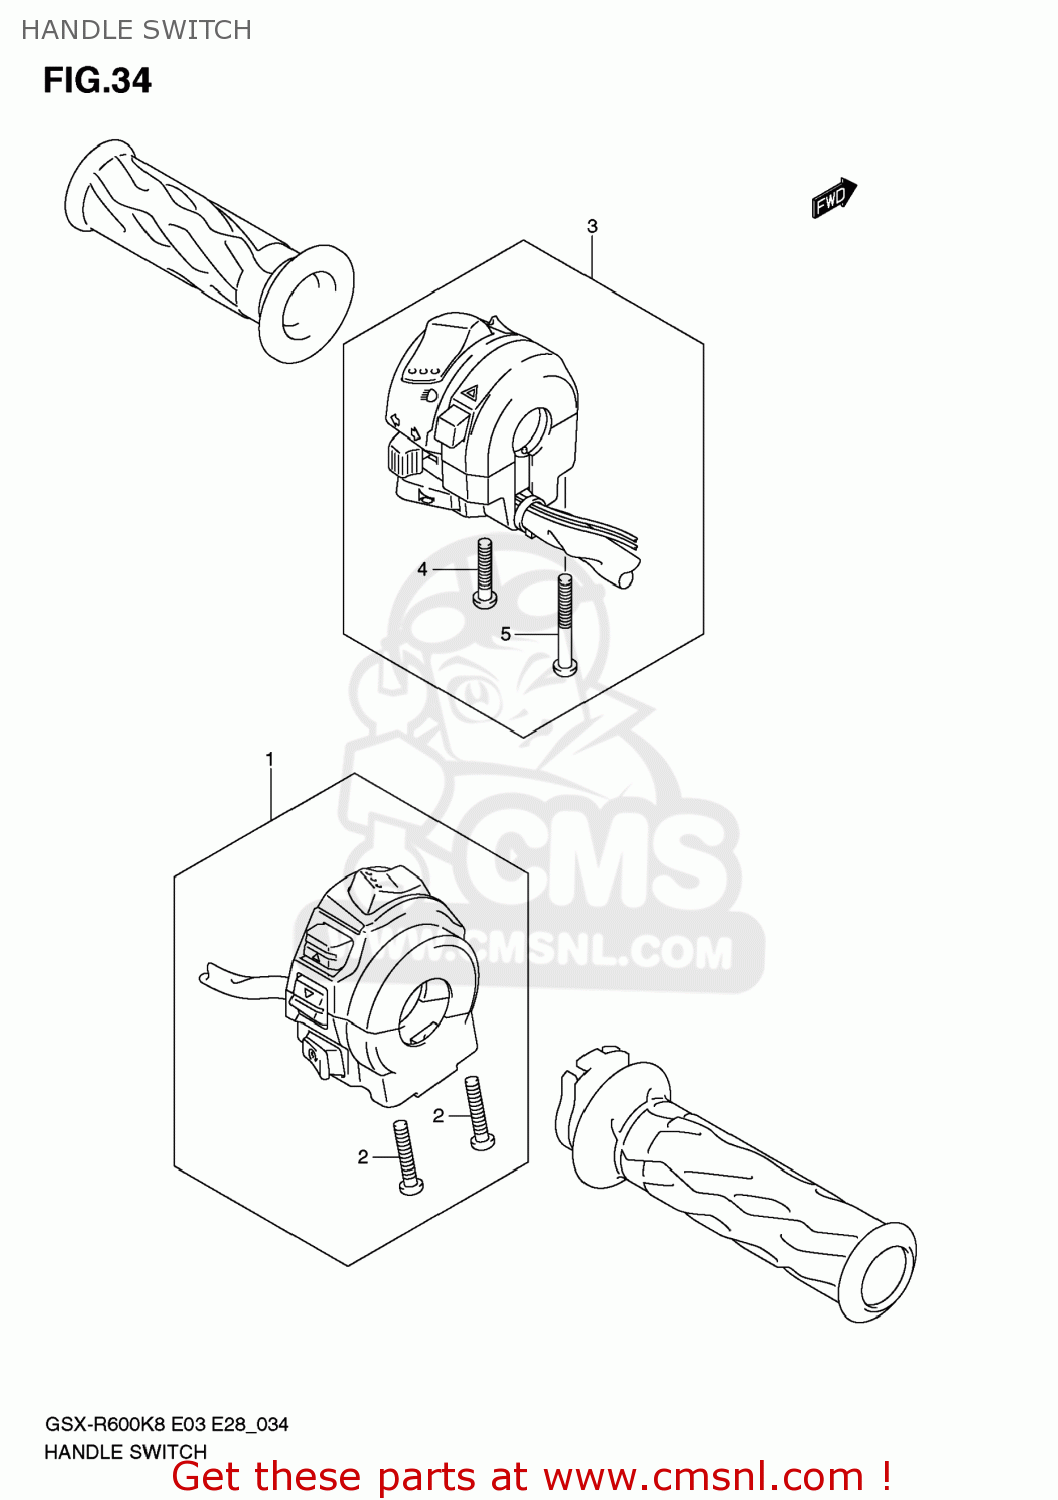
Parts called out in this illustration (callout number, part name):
1	SWITCH ASSY,HANDLE,R
2	SCREW
3	SWITCH ASSY,HA
4	SCREW
5	SCREW
